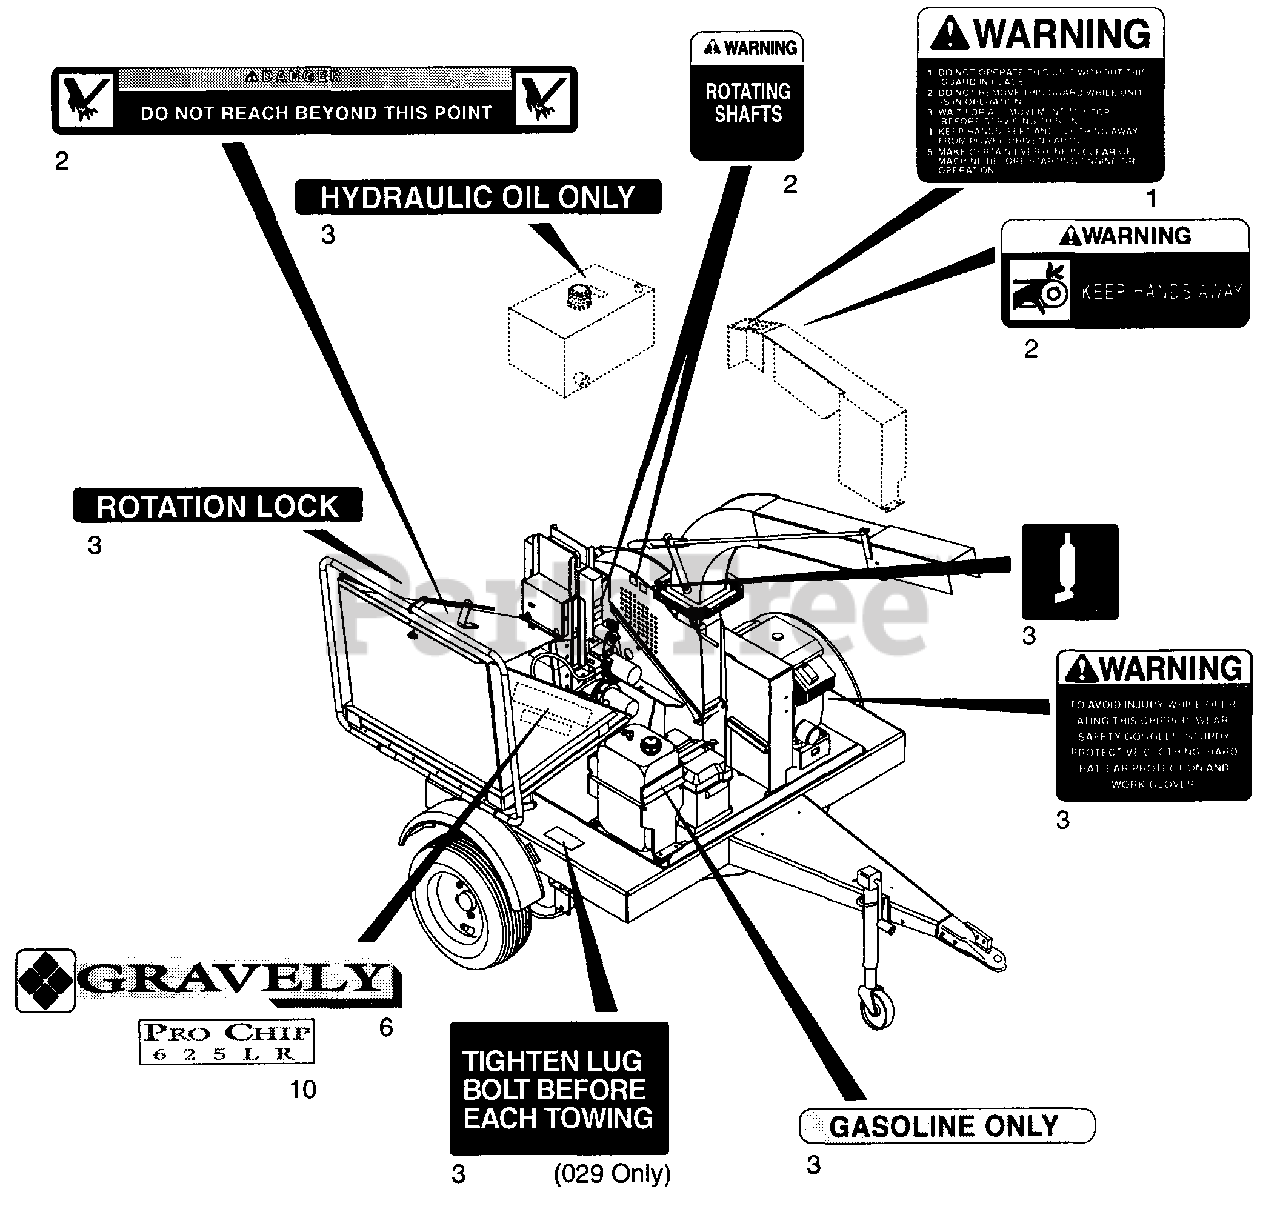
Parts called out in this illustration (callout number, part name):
1	Decal Set
2	Decal Set Large Chipper
3	Decal Set Chipper Blk/Wht
6	Gravely Name Logo Set
7	Decal - Pro Chip 625LR
8	Decal - Warning, Protective
9	Decal - Hot Surface
10	Decal - Model Designation 625LR
